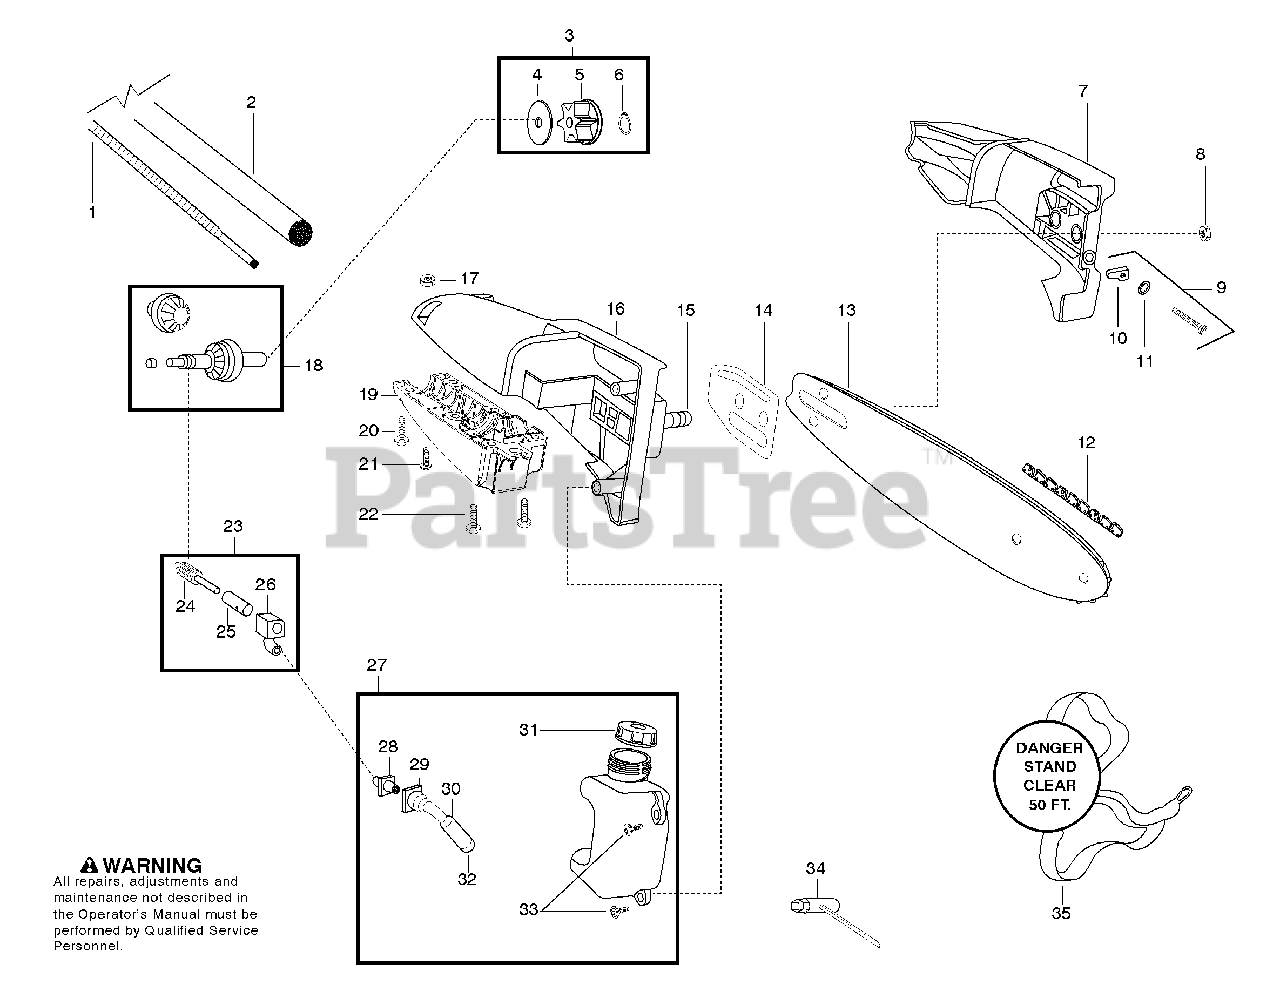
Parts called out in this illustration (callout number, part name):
1	Flexshaft - lower
2	Assy. - Lower Driveshaft
3	Kit - Sprocket Assy.
5	Sprocket
6	Retainer - Sprocket
7	Assy - Bar Clamp
8	Nut - Bar Mounting
9	Kit - Bar Adjust
10	Pin - Bar Adjust
11	Retainer - Bar Adjust
12	Chain - 8"
13	Bar - 8"
14	Plate - Bar Pad
15	Bolt - Bar
16	Housing - Upper
18	Kit - Gear Assy.
19	Housing - Lower
21	Screw - Alignment
23	Kit - Oil Assy
24	Assy. - Gear Plunger
26	Assy- Oil Block
27	Assy - Oil Tank
28	Fitting - Oil Line
29	Intake - Oil Line
30	Filter - Oil
31	Cap - Oil
32	Plug - Oil Filter
34	Wrench - Bar
35	Strap-Shoulder
